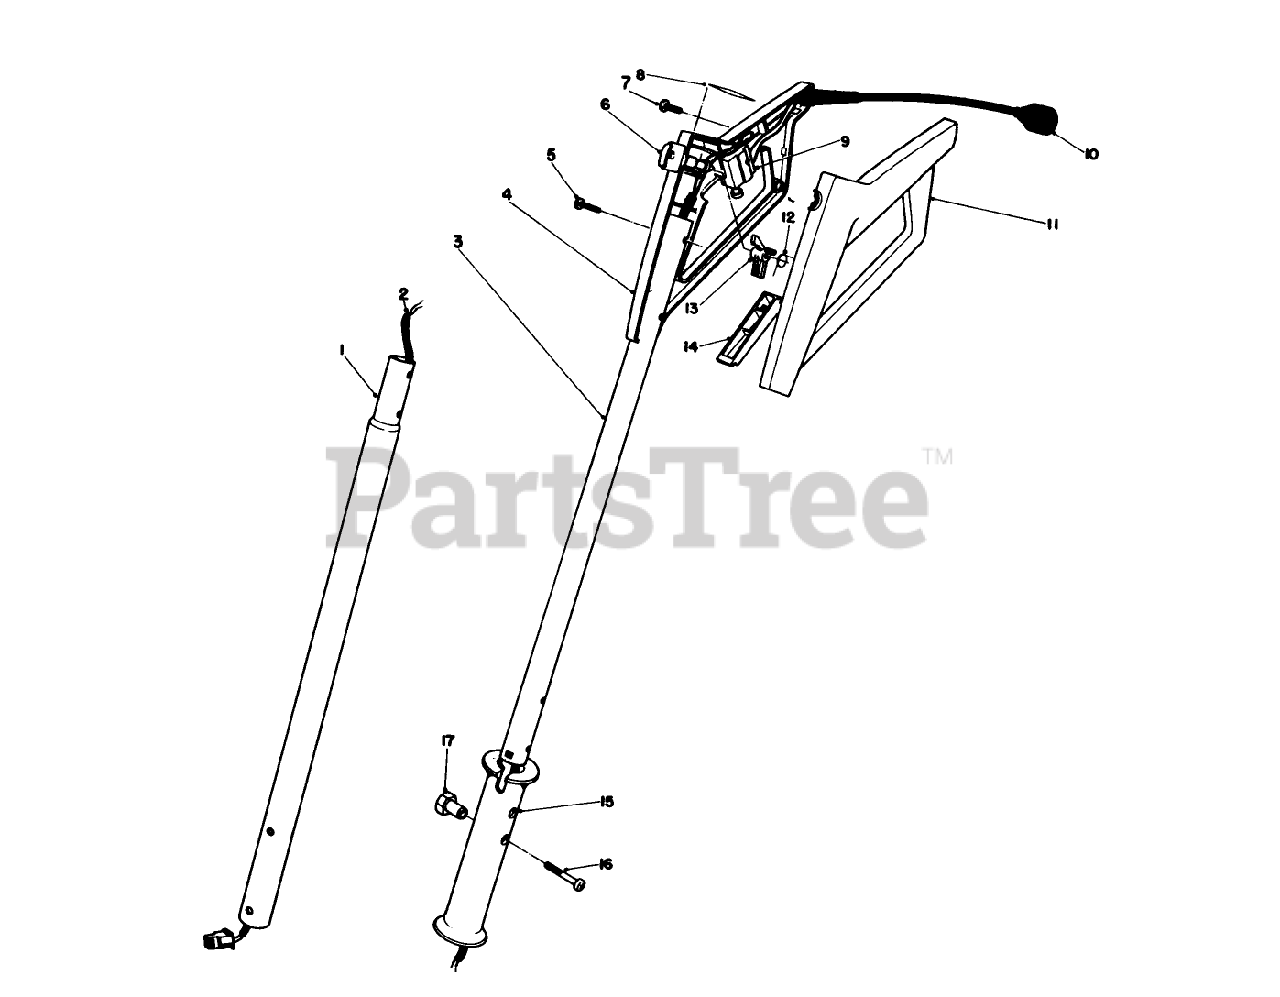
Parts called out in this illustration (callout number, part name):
2	Frame Bag
7	SCREW-PPH
8	UL GRIP DECAL
9	Switch
10	Cord-Supply
12	TORSION SPRING
13	LOCKOUT
14	SWITCH BAR,POWER SHOVEL
16	SPEC PAN HD SCREW
17	SPECIAL HEX NUT
